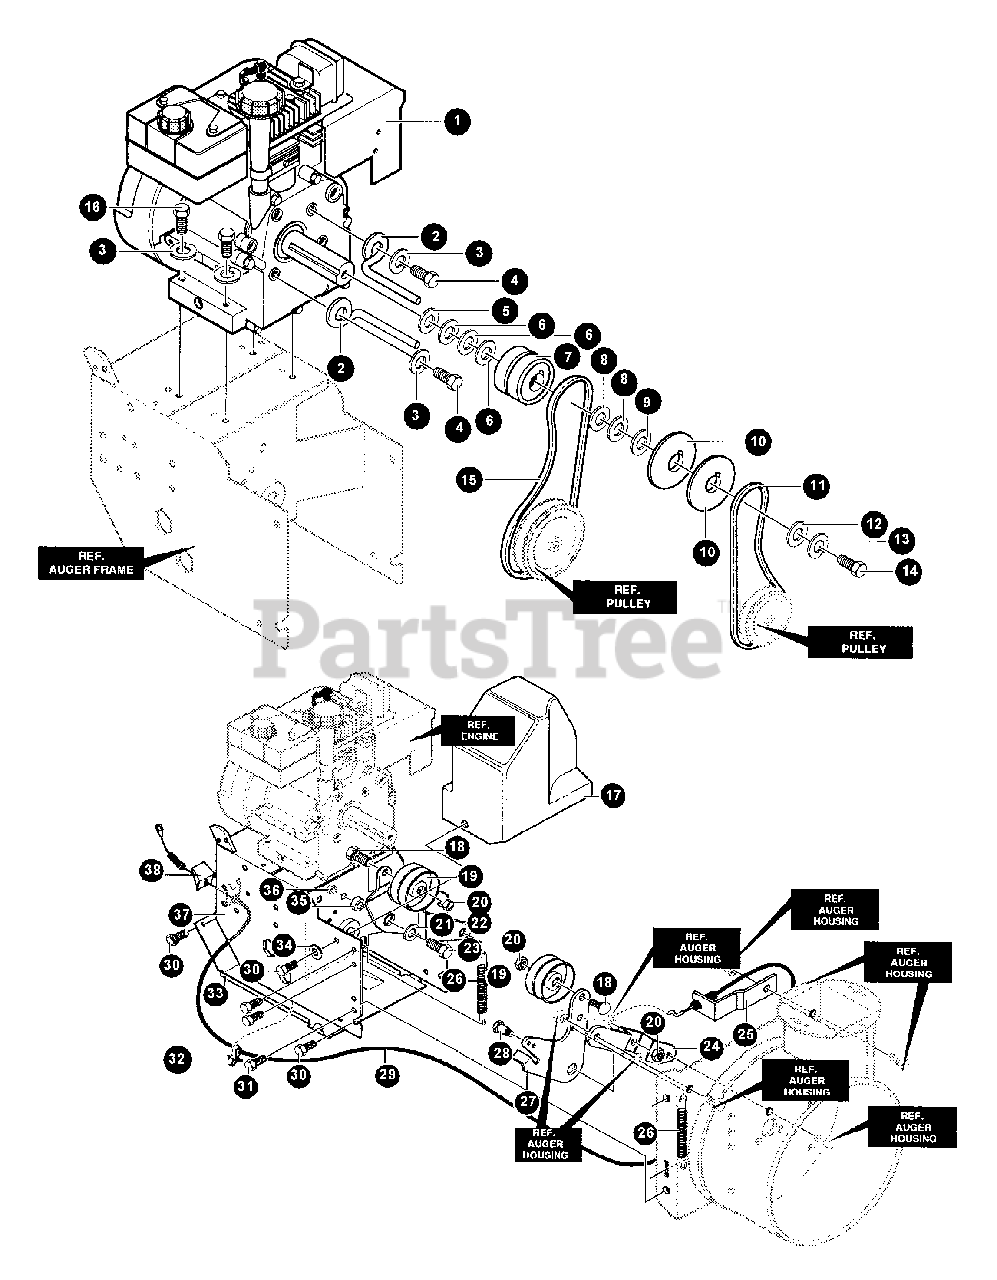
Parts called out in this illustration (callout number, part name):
2	GUIDE, ROD BELT - RIGHT
3	WASHER
4	SCREW - 5/16-24×0.625" -- HEX HEAD CAP
5	WASHER, CRANKSHAFT
6	WASHER, FLAT 0.752×0.91×0.02
7	PULLEY, HALF
8	WASHER, FLAT
9	SPACER
10	PULLEY, ENGINE
11	BELT, V 4L 35.23 LG
12	WASHER
13	WASHER. REGSPTLK 0.393×0.68×0.10
14	SCREW - 3/8-24×1.00" -- NYLON HEX HEAD
15	BELT
16	SCREW - 5/16-18
17	COVER, BELT
18	SCREW - 3/8-16×1.25" -- HEX HEAD CAP
19	PULLEY, IDLER
20	LOCKNUT - 3/8-16
21	WASHER, FLAT 0.328×1.25×0.075
22	LEVER, IDLER ARM TRACTION
23	SCREW 5/16"-18×0.75
24	PLATE, CLUTCH
25	BRACKET, COMPACT CABLE MTG.
26	SPRING, IDLER
27	ARM, CLUTCH
28	BOLT - 3/8-16
29	CABLE, AUGER
30	SCREW 1/4"-20×0.63
31	SCREW, 5/16-18×0.50 WAHHTAP
32	CLIP, CABLE TINN #D98281-017
33	COVER, BOTTOM
34	WASHER
35	BUSHING, IDLER LEVER
36	NUT, 5/16 - 18
37	FRAME ASSY
38	SHIELD, CABLE GUARD
